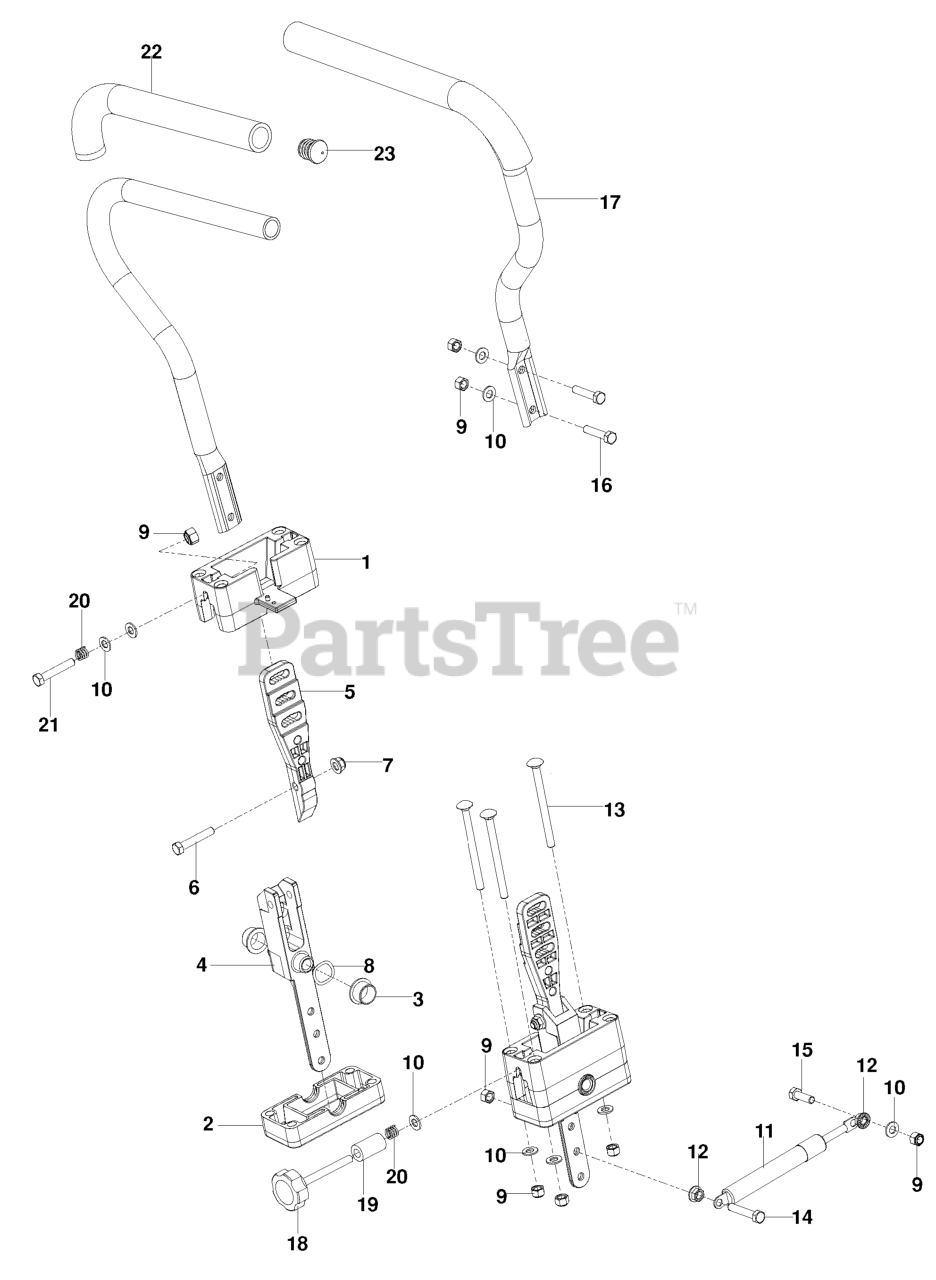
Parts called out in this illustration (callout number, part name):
1	BLOCK, UPPER
2	BLOCK, LOWER
3	BEARING, FLANGE
4	PIVOT.SECTION.DRIVE.CONTROL
5	MOUNT, DR CNTRL HANDLE
6	HCS 5/16C X 1 3/4
7	5/16-18 NYLOC FLANGE NUT
8	WASHER, .825 X 1.087, WAVE
9	NUT 5/16 NYLOC
10	FLAT WASHER 5/16 SAE
12	NUT 5/16C WHIZ
13	RHSNB 5/16-18 X 4 GR 5 ZD
14	HCS 5/16-18X1-3/4 TPBLT
15	HCS 5/16C X 1
16	CAPSCREW 5/16 X 1/1/2 HEX HEAD
17	LEVER.DRIVE.W/GRIP
21	HCS 5/16-18 X 2 TPBLT GR 5 ZD
22	GRIP, FOAM (GROUND) 15
23	END PLUG 15/16 (BLACK)
